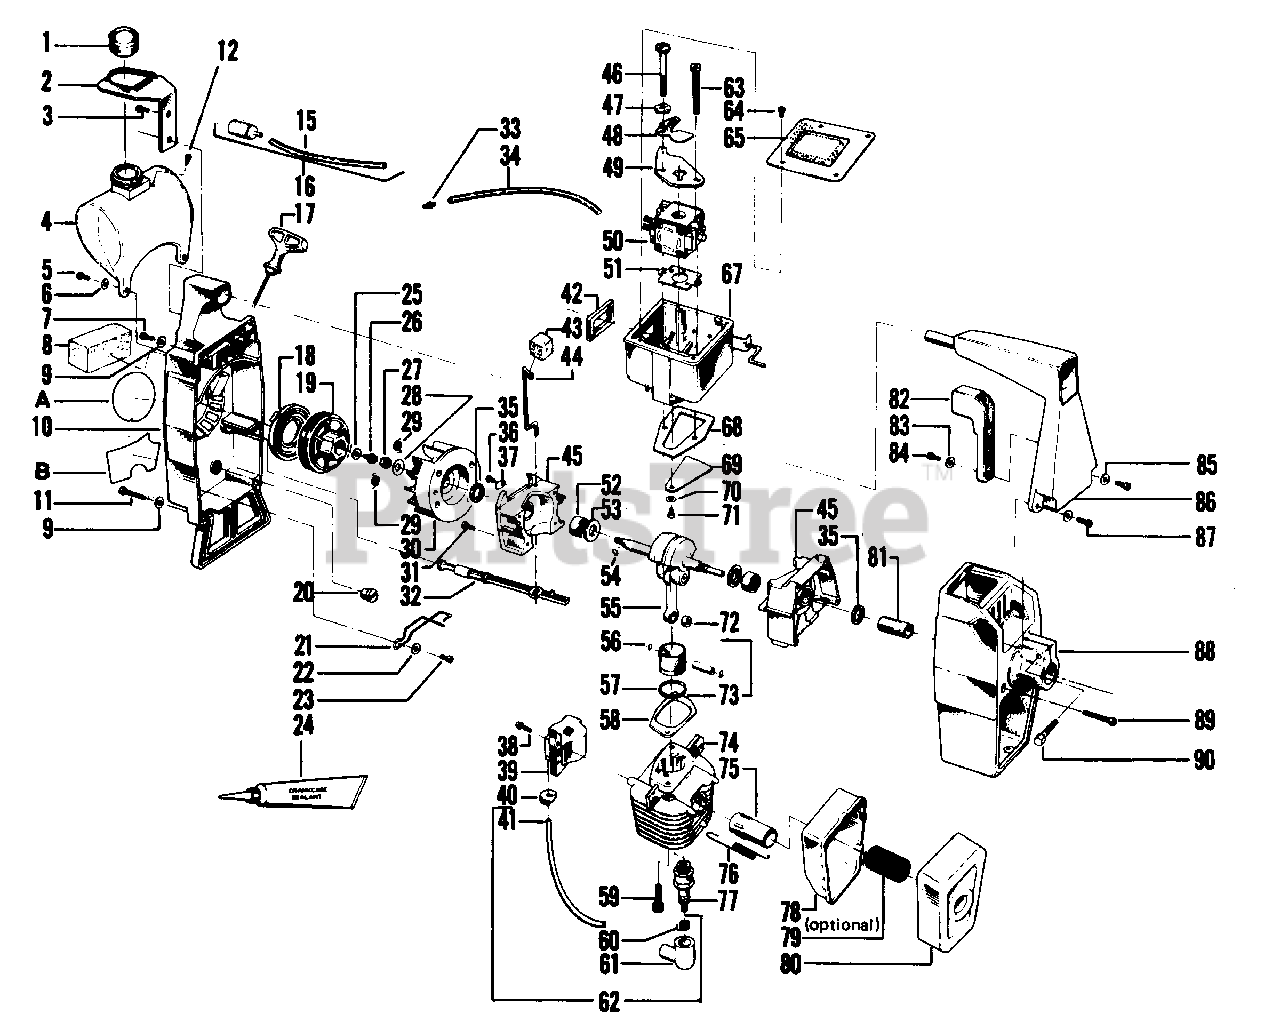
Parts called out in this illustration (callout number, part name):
1	Fuel Cap Assembly
2	Bracket - Fuel Tank
3	Screw - Bracket/Handle (1/4 - 10 x 1-1/8)
4	Fuel Tank (Inc. # 12)
5	Screw - Fuel Tank/Fan Housing (10 - 1)
6	Washer - Fuel Tank/Fan Housing
7	Screw - Fan Hsg. Top #10 - 24 x 5/8 Fil.
8	Air Filter
9	Washer - Flat - Fan Housing
10	ARMATURE ASSY.1.0"STK 10 PARAM
11	Screw - Fan Housing - Bottom - #10 - 24 x 1-3/16 Fil.
12	Check Valve - Duck Bill
15	Line - Fuel Pick-up
16	Fuel Line & Filter Assembly (Inc. # 15)
17	Rope & Handle - Starter
18	Starter - Recoil Spring
19	Starter - Pulley
20	Button - Kill Switch
22	Washer - Kill Switch
23	Screw - Kill Switch (8 x 3/8)
24	Crankcase Sealant - 3 oz. tube (Optional)
25	Washer - Starter Pulley
26	Screw - Starter Pulley (#10 - 3/4 - Hex Head)
27	Nut - Flywheel (5/16 x 24)
28	Washer - Flywheel
29	Spring - Starter Dog
30	Flywheel Ass'y (Inc. #28)
31	Screw - Crankcase (# 10 - 24 x 5/8 Fil.)
32	Knob - Choke
33	Fitting - Fuel Line
34	Fuel Line - Carburetor
35	Seal - Crankshaft
36	Screw - Clamp # 8 - 32 x 5/16 Pan.
37	Clamp - Choke Wire
38	Screw - Ignition Module (8 - 32 x 3/4 - Sems)
39	Kit - Ignition Module (Inc. 21)
40	Grommet - Plug Wire
41	Lead Wire - High Tension
42	Seal - Carburetor Case
43	Boot - Choke Wire
44	Wire - Choke
45	Crankcase Ass'y (Inc. #35 & 52)
46	Screw - Carburetor (Shoulder #10 - 24)
47	Wave Washer
48	Shutter - Choke
49	Plate - Guide, Choke Wire
50	Carburetor (WA-149)
51	Gasket - Carburetor
52	Bearing - Crankshaft
53	Thrust Washer - Crankshaft
54	Key - Flywheel
55	Crankshaft & Rod Assembly
56	Retainer - Wrist Pin
57	Piston Ring
58	Gasket - Cylinder
59	Screw - Cylinder (1/4 - 20 x 3/4 Socket Head)
60	Connector - Spark Plug
61	Boot - Spark Plug
62	BEVEL GEAR COMPLETE
63	Screw - Carburetor (#10 - 24 Fil.)
64	Screw - Carburetor Cover (8 - 18 x 9/16)
65	Cover - Carburetor Case
67	Carburetor Case Assembly
68	Gasket - Carburetor Case/Crankcase
69	Reed Valve
70	Washer - Reed Valve
71	Screw - Reed Valve (6 - 19 x 5/16)
72	Bearing - Wrist Pin
73	Piston Ass'y (Inc. # 56, 57 and Pin)
74	Cylinder
75	Diffuser - Muffler
76	Spring - Muffler Attachment
77	Spark Plug (CJ-14)
78	Body - Muffler
79	Screen - Spark Arrestor Kit (optional)
80	Cover - Muffler
81	Coupling - Hex Drive
82	Trigger - Throttle
83	Washer - Throttle
84	Screw - Throttle (8 - 16 x 3/8)
85	Washer - Flat - Shroud
87	Screw - Shroud (Top) - (10 - 24 x 7/8)
89	Screw - Shroud (Bottom) - #10 - 24 x 1-1/2 Fil.
90	Bolt, Pinch Clamp (1/4 - 20 x 1 - Hex Cap)
A	Decal - Starting Instructions
B	Decal - Choke / OFF
